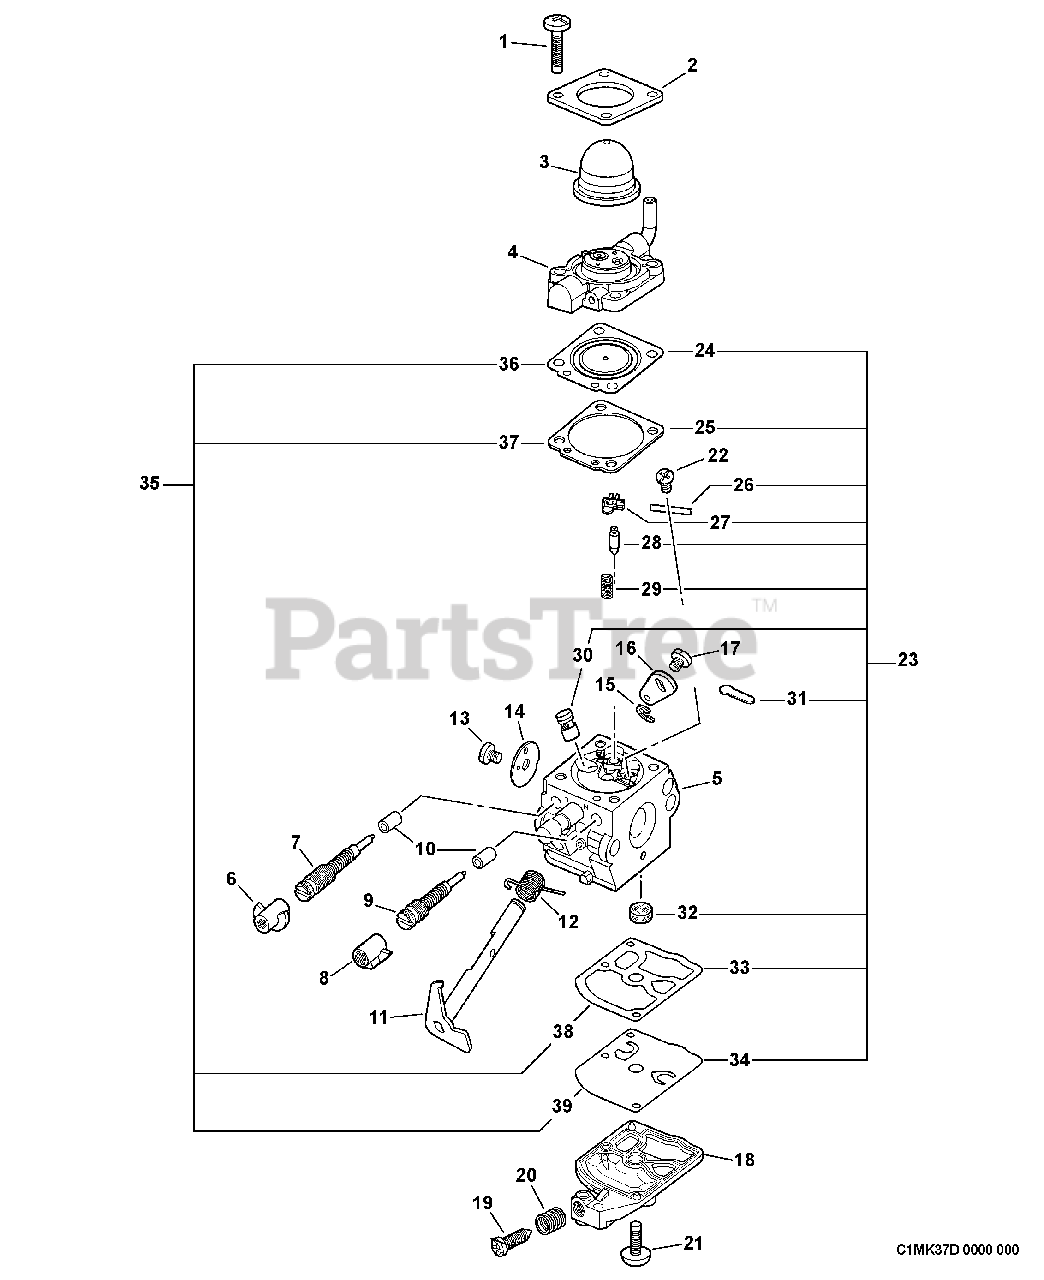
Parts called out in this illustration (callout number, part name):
1	SCREW, RETAINER
2	RETAINER, PURGE BULB
3	BULB, PURGE
4	BASE, PURGE
5	BODY, CARBURETOR
6	CAP, LIMITER
7	NEEDLE - LOW SPEED
8	CAP, LIMITER
9	NEEDLE - HIGH SPEED
10	RETAINER
11	SHAFT, THROTTLE
12	SPRING, TRIGGER
14	VALVE, THROTTLE
15	RING, RETAINING
16	LEVER, THROTTLE
18	COVER, FUEL PUMP
19	SCREW, IDLE ADJUST
20	SPRING, IDLE ADJUST
21	SCREW, PUMP COVER
22	SCREW, METERING LEVER PIN
23	REPAIR KIT
24	DIAPHRAGM, METERING
25	GASKET, METERING
26	PIN, METERING LEVER
27	LEVER, METERING
28	VALVE, INLET NEEDLE
29	SPRING, METERING LEVER
30	NOZZLE, CHECK VALVE
31	PLUG, WELCH
32	STRAINER
33	DIAPHRAGM, PUMP
34	GASKET, PUMP
35	DIAPHRAGM/GASKET KIT
36	DIAPHRAGM, METERING
37	GASKET, METERING
38	DIAPHRAGM, PUMP
39	GASKET, PUMP
